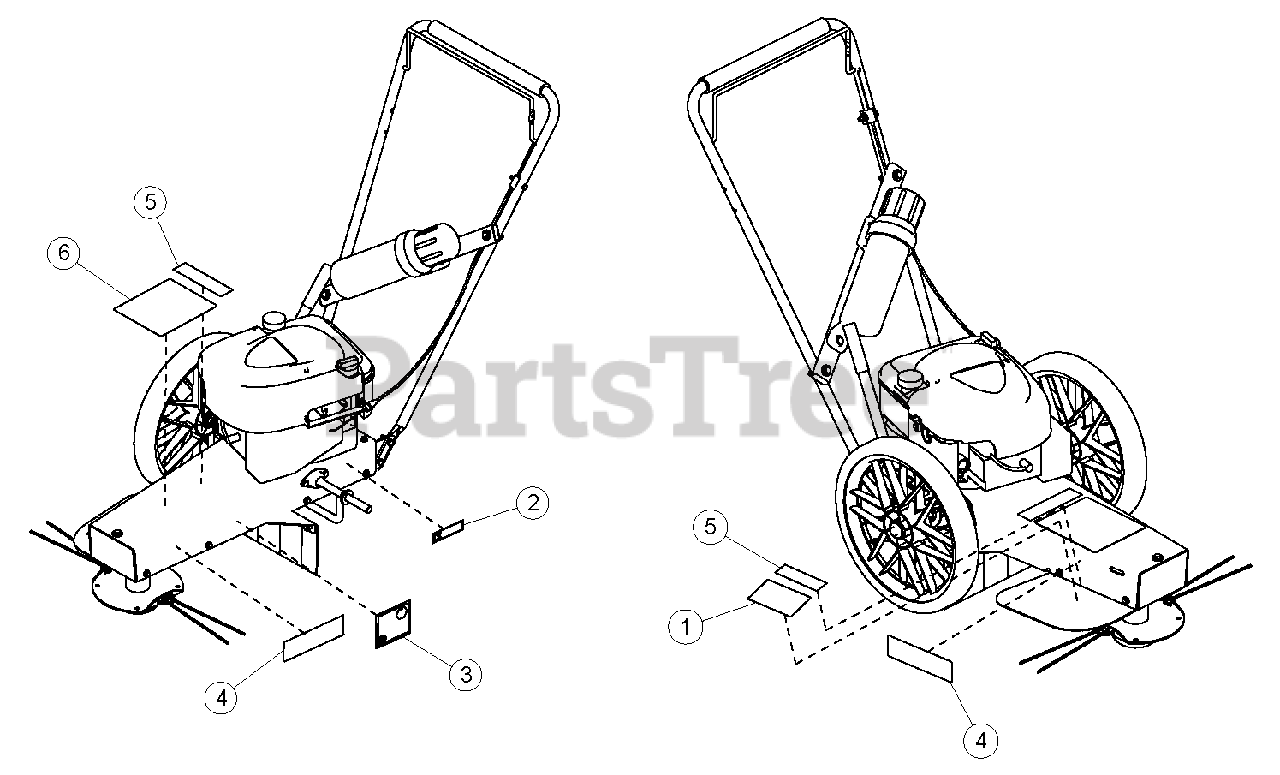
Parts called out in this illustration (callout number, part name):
1	DECAL, CUTTER DANGER
2	DECAL, 5.5 HP INFORMATION (WT160S, WT160T)
3	DECAL, SMALL BEARCAT (DOMESTIC & G-MODELS)
4	DECAL, SMALL BEARCAT (S-MODELS)
5	DECAL, MODEL WT190
6	DECAL, MANUAL/SAFETY
